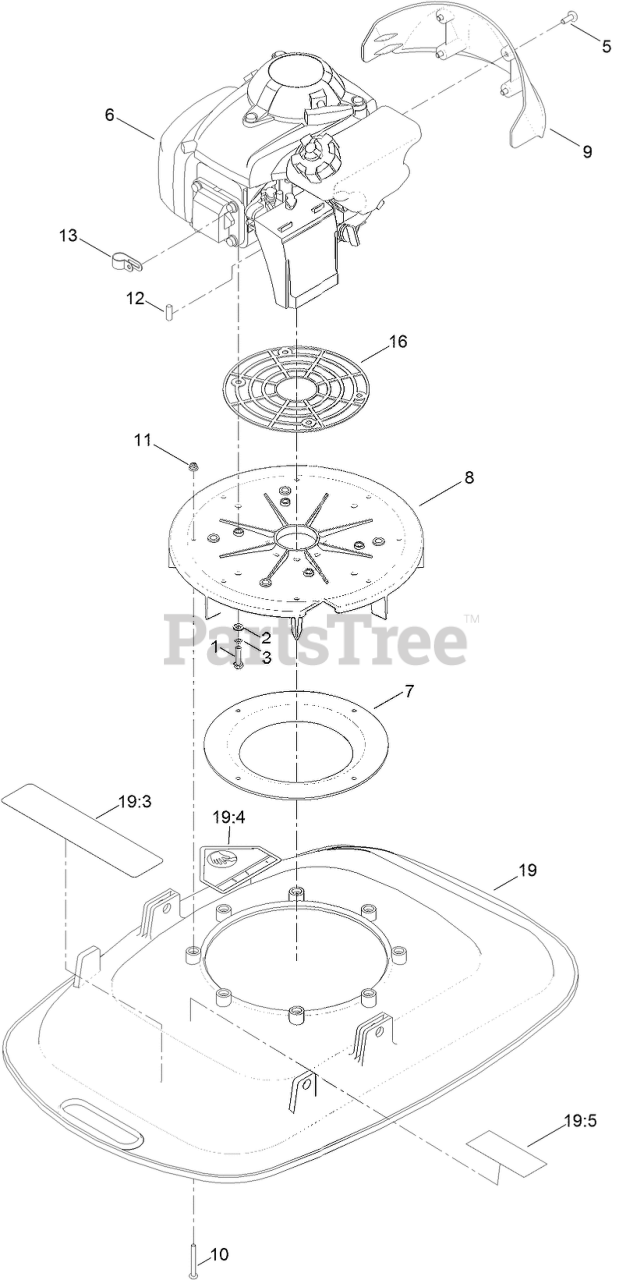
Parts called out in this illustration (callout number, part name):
1	SCREW-HH
2	WASHER-PLAIN
3	WASHER-SPRING
5	SCREW-SOC, HD
6	ENGINE-HONDA
7	BELL-MOUTH
8	PLATE-ENGINE
9	COVER-SUMP
10	SCREW-PPH
11	NUT-HHF, NY
12	KEY-DRIVE, SQUARE ENDED
13	CLIP-P, NATURAL
16	SINK-HEAT
19:3	DECAL-WARNING
19:4	DECAL-DANGER
